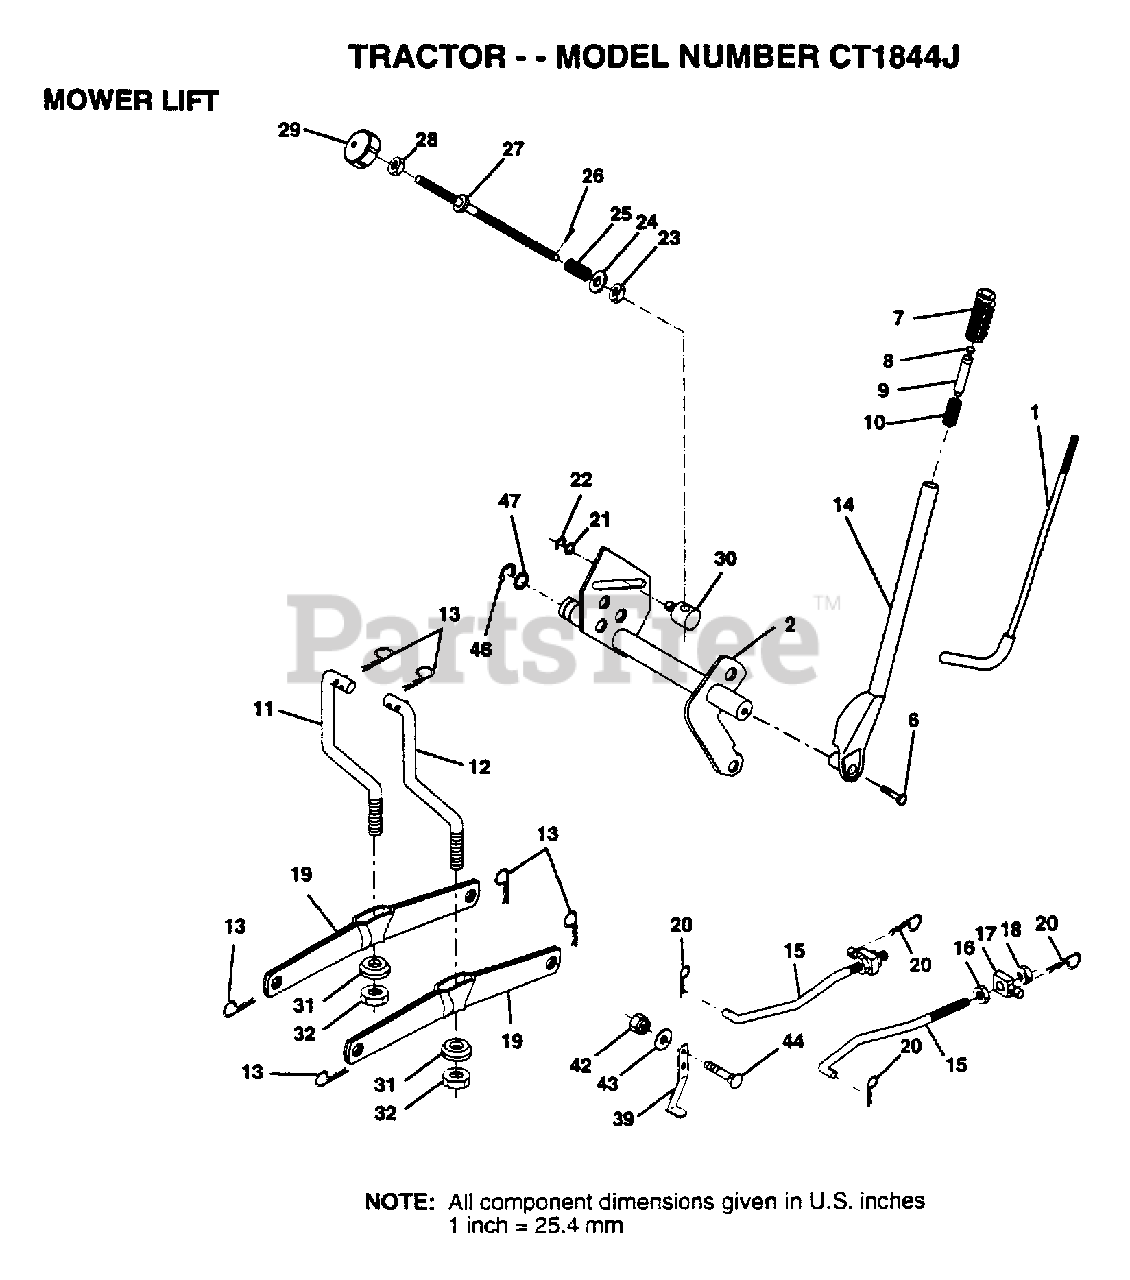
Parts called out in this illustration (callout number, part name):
1	LEVER ROD LT
2	SHAFT LIFT W/IND
6	"BOLT,HEX"
7	GRIP
10	SPRING T
11	LINK.LIFT.LH.GTV
12	LINK.LIFT.RH.GTV.
15	LINK.FRONT
16	NUT
17	TRUNION
18	NUT.LK.W/WSH.1/2.
19	ARM SUSP REAR
20	RETAINER.SPRING
21	WASHER
22	KLIP RING
23	NUT T
24	WASHER
25	SPRING.COMP.INF.H
27	ROD.ADJ.LIFT
28	NUT
29	KNOB INF 3/8-16
30	TRUNION LT
31	BEARING PVT LH
32	NUT.CROWNLOCK.3/8
39	STOP.OVER.CENTER
43	WASHER GT
44	BOLT
46	E-RING
47	WASHER
